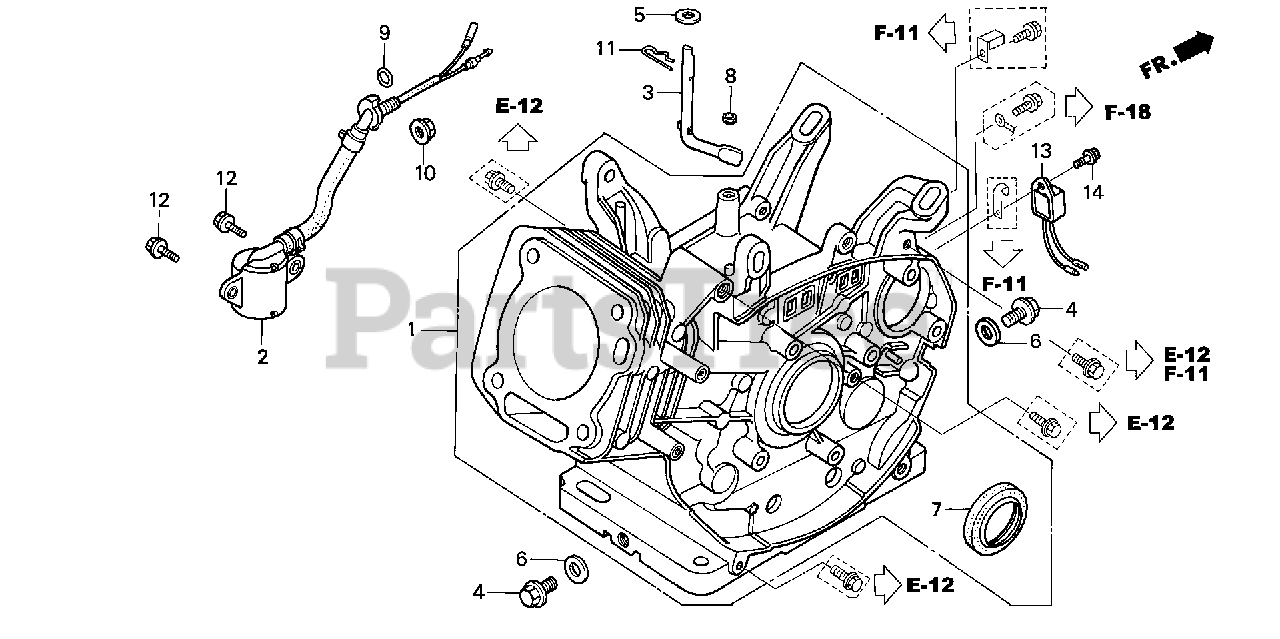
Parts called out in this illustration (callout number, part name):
1	CYLINDER ASSY. (SELF STARTER+ALERT)
2	SWITCH ASSY., OIL LEVEL
3	SHAFT, GOVERNOR ARM
4	BOLT, DRAIN PLUG
5	WASHER (8.2X17X0.8)
6	WASHER, DRAIN PLUG (12MM)
7	OIL SEAL (30X46X8)
9	O-RING (14MM) (ARAI) Use up to Engine SN 2949254.
9	O-RING (14MM) (NOK)
10	NUT, FLANGE (10MM)
11	PIN, LOCK (10MM)
12	BOLT, FLANGE (6X12) Use up to Engine SN 1543277.
13	ALERT UNIT, OIL
14	BOLT, FLANGE (6X12) (CT200)
